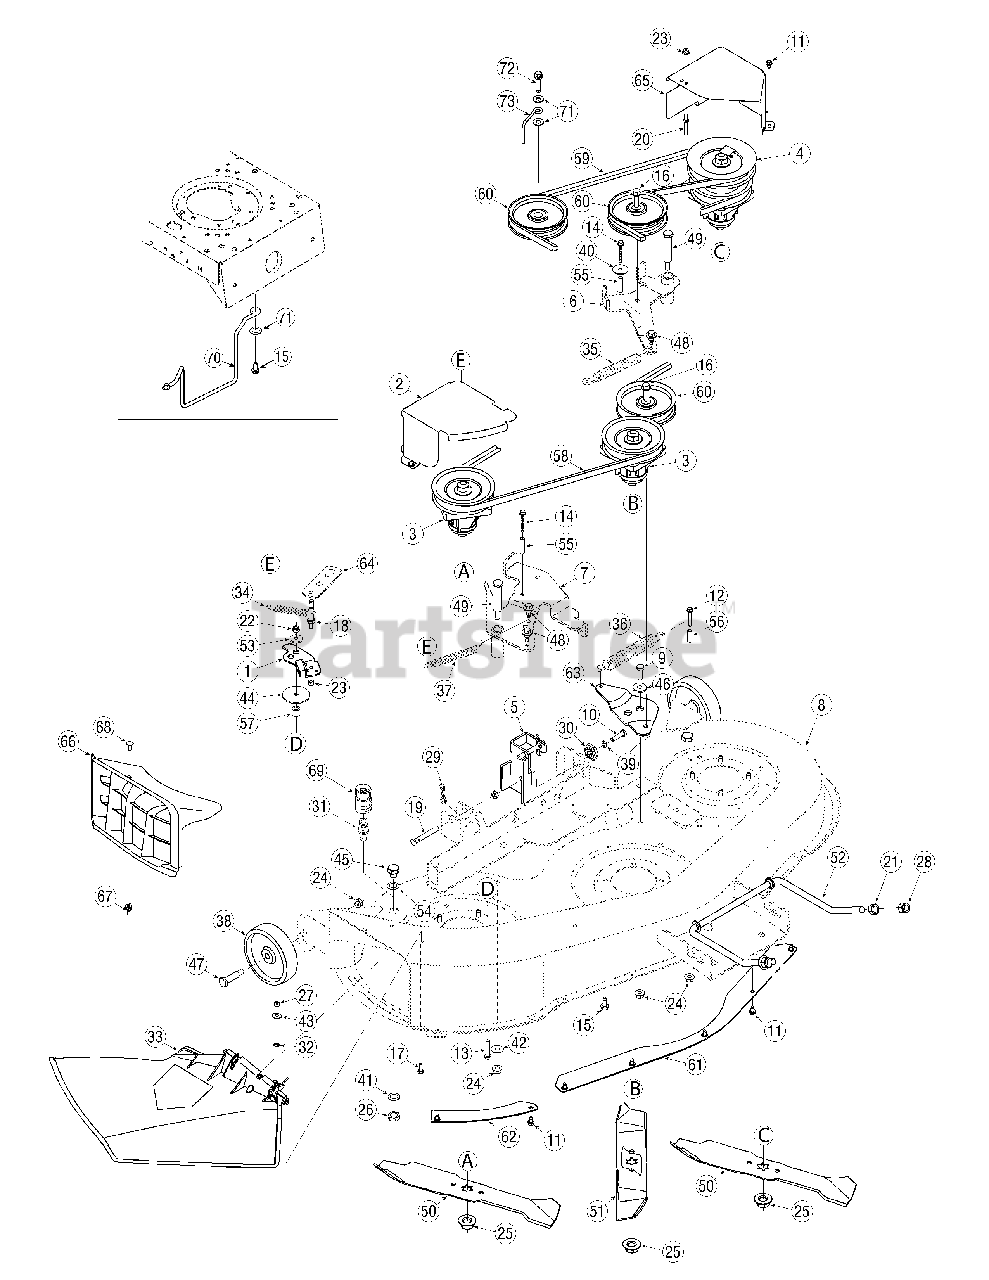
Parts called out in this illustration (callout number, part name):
1	Deck Brake Bracket Ass’y
2	Belt Cover Brkt RH
3	Spindle Assembly, 5.0 Dia.
4	Spindle, Double Pulley 46" Deck
5	Deck Adjustment Bracket w/Weld Nut
6	Idler Bracket Assembly - LH
7	Idler Bracket Assembly - RH
8	46" Deck (shell)
9	Hex Screw 3/16 x 1.00
10	Hex Bolt 5/16-18 x 1.25
11	Hex Wash S-Tapp Scr 1/4-20 x .50
12	Hex Wash HD Bolt 1/4-20 x 1.50" Lg.
13	Hex Bolt 5/16-18 x 1,50" Lg. Gr. 5
14	Hex TT-Tap Scr 1/4-20 x 1.75
15	Hex TT Hd. Scr. 5/16-18 x .75 Lg.
16	TT Screw 3/8-16 x 1.25
17	Hex Cap Bolt 1/4-20 x .75" Lg.
18	Pin, 1/4-20, 3/8 x 2.0
19	Clevis Pin, 3/8 x 2.75
20	Belt Guard Pin
21	Hex Nut 1/2-13
22	Flange Locknut 5/16-18 Gr. F, Nylon
23	Hex L-Flanged Nut 1/4-20 Gr. F Nylon
24	Flange Lock-Nut 3/8-16 Gr. F Nylon
25	Hex Flange Nut 5/8-18
26	Hex Nut M16-1.5 DIN 936
27	Hex Nut 1/4-20 Gr. 5
28	Hex Nut, 1/2-13
29	Bow Tie Cotter Pin 1/8 x 1.25
30	Deck Adjustment Gear
32	Bolt Retainer 1/4" x .50" OD
33	Chute Deflector (Plastic)
34	Tension Spring .50 OD x 3.97" Lg.
35	Extension Spring .75 x 6.835
36	Extension Spring
37	Extension Spring
38	Wheel Ass’y - Deck 5" x 1.38"
39	L-Wash 5/16 ID
40	Flat Washer .285 ID x 1.25 OD x .060
41	L-Washer Internal
42	Flat Washer .385 ID x 1.0 OD x .130
43	Cupped Washer .265 ID x .75 OD x .062
44	Flat Washer .34 ID x 2.25 OD x .100
45	Screw Plug M16 x 1.50
46	Shoulder Spacer
47	Shoulder Bolt .498 Dia x 1.53 x 3/8-16
48	Shoulder Screw .43 x .29, 5/16-18
49	Shoulder Screw .625 x 2.515 x .875
50	Three-in-one Blade, Star 16.28"
51	Three-in-one Blade, Star 14.88"
52	Deck Front Hanger Rod
53	Shoulder Spacer .25 THK
54	Flat Washer .640 ID x 1.24 OD x .06
55	Spacer .260 x .372 x 1.420
56	Spacer .260 x .375 x 1.030 Lg.
57	Spacer .375 x .63 x .595
59	Belt, V-type, à x 90.24
60	Idler Pulley w/Flange 4.25 Dia
61	Center Deck Skirt
64	Brake Bracket 46"
65	Belt Cover LH
66	Mulching Plug
67	Wing Nut 1/4-20 Thd.
68	Carriage Bolt 1/4-20 x .62
69	Water Nozzle Adaptor
70	Belt Keeper Rod
71	Flat Washer .385 ID x .87 OD x .06
72	Hex L-Wash HD Scr 3/8-16 x 1.5
73	Belt Keeper Rod, 42" Idler
